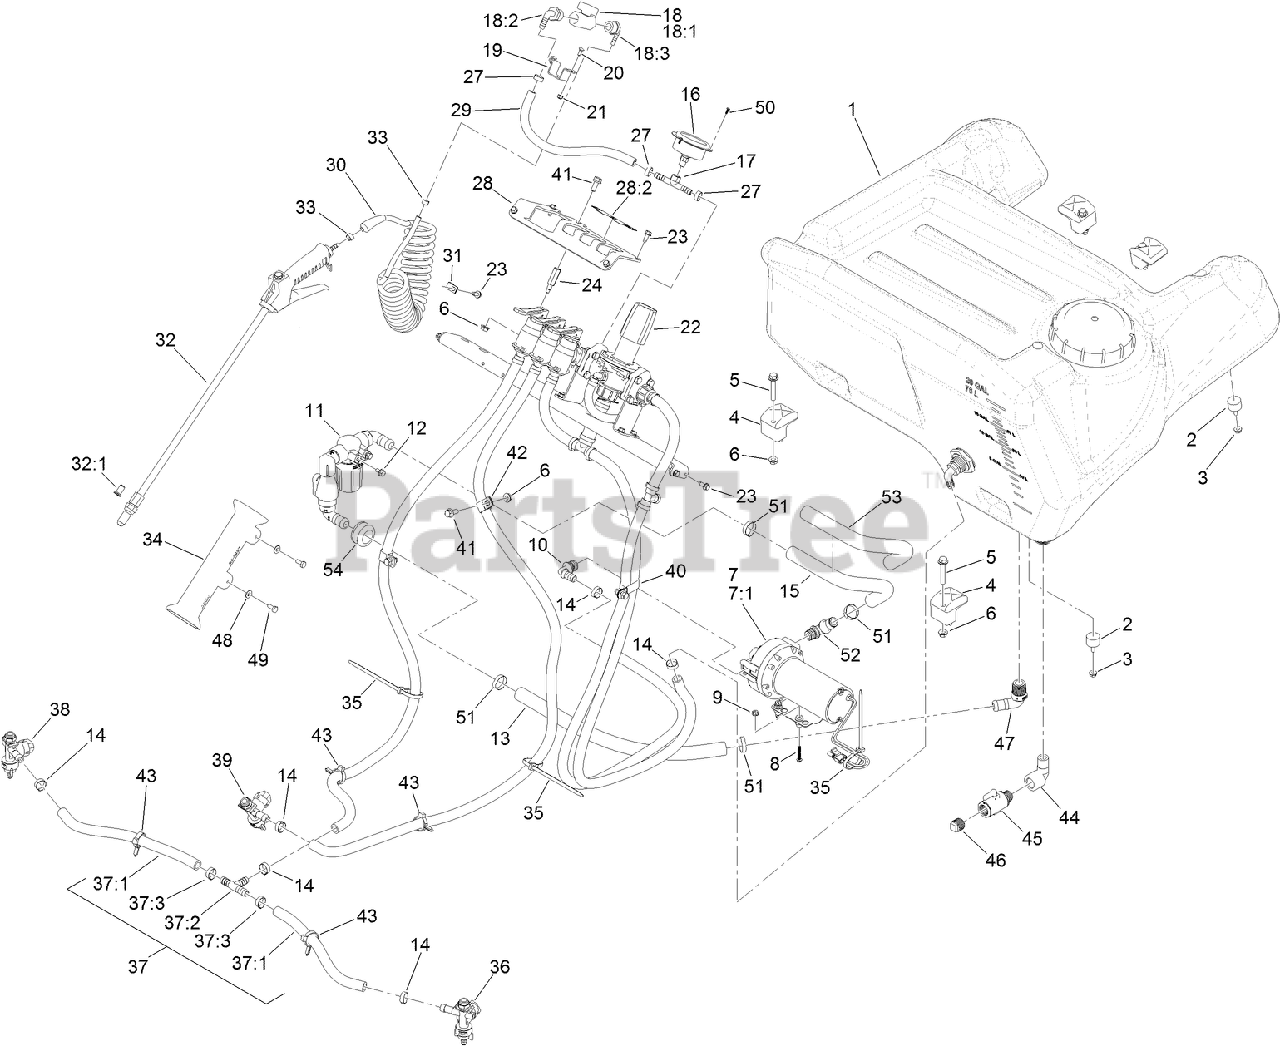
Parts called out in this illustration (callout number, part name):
1	TANK-SPRAYER
2	BUMPER
3	NUT-HF
5	SCREW-HHF
6	NUT-HF
7	PUMP-DIAPHRAGM, 3.8 GPM
7:1	KIT-DIAPHRAM PUMP
8	SCREW-SHWH
9	NUT-HF
10	FITTING-ELBOW, BARBED
11	STRAINER ASM
12	SCREW-HHF
13	HOSE-WATER
15	HOSE-WATER
16	GAUGE-PRESSURE
17	FITTING-TEE
18	WAND CONTROL ASM
18:1	VALVE-BALL
18:2	FITTING-ELBOW-90
18:3	FITTING-ELBOW-90
19	BRACKET-VALVE
20	BOLT-CARR
21	NUT-LOCK, NI
22	CONTROL VALVE MANIFOLD ASM
23	SCREW-HWH
24	SPACER-MOUNT, MANIFOLD
28	COVER-CONTROLS
28:2	DECAL-CONTROL, LEVER
29	HOSE-WATER, 3/8 PVC RED
30	HOSE-COILED
31	CLAMP-R
32	SPRAY WAND ASM
32:1	STRAINER-NOZZLE, 50M 5PSI CHECK
34	HOLDER-WAND
35	TIE-PLASTIC
36	LEFT NOZZLE SUB ASM
37	HOSE ASM
37:1	HOSE-WATER
37:2	FITTING-TEE
38	RIGHT NOZZLE SUB ASM
39	CENTER NOZZLE SUB ASM
41	SCREW-HHF
42	CLIP-LOOM
43	CLAMP-HOSE
44	ELBOW-90 DEG
45	MICROVALVE
47	ELBOW-HOSEBARB
48	WASHER-FLAT
49	SCREW-HH
50	SCREW-TAP
52	FITTING-ELBOW
53	SLEEVE-CORRUGATED, SPLIT
54	GROMMET
